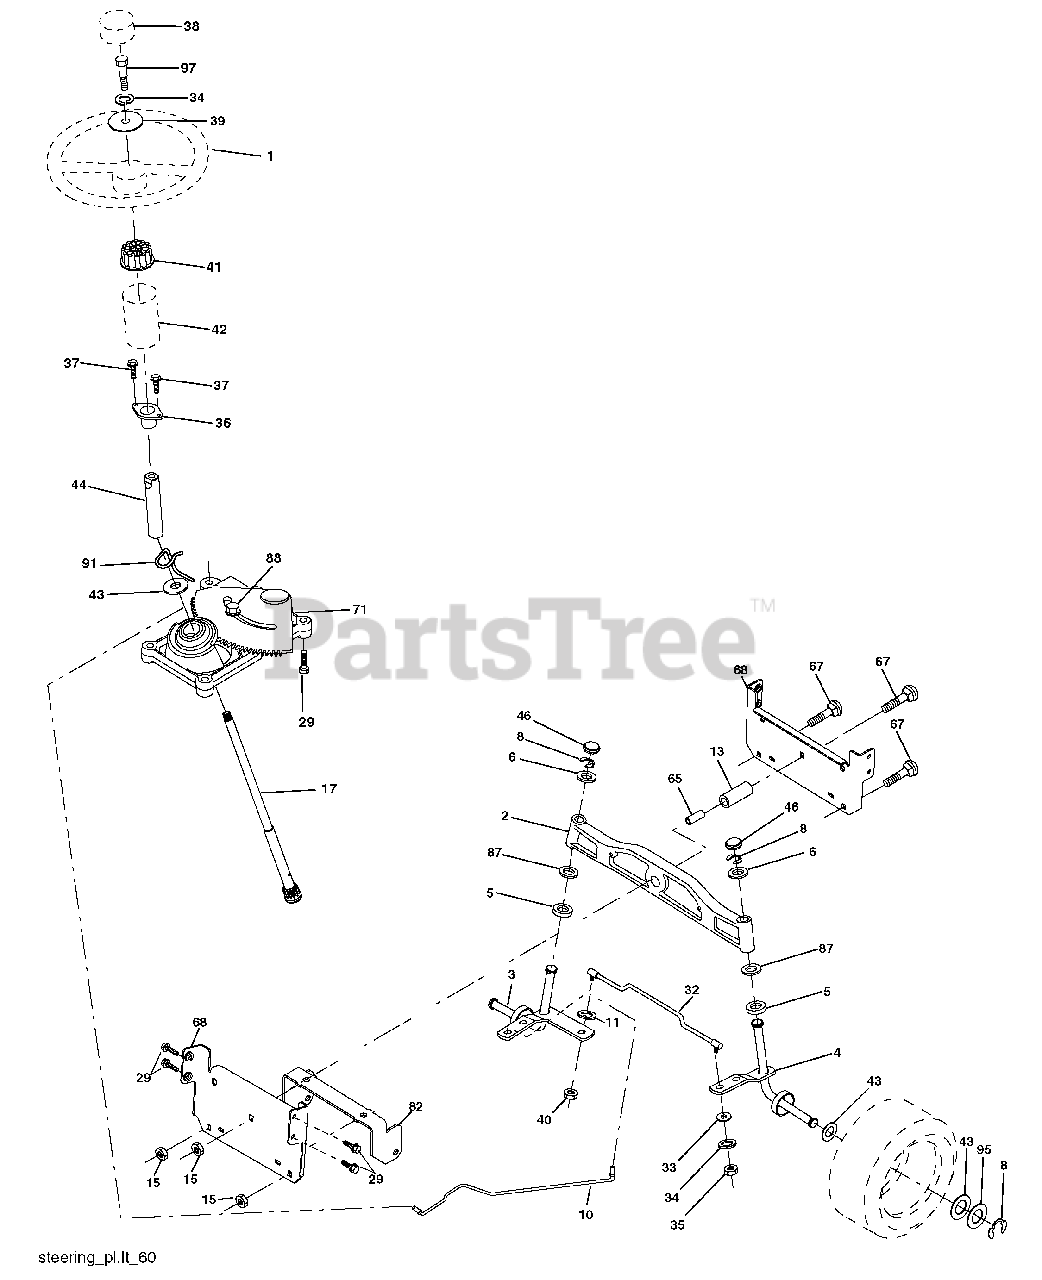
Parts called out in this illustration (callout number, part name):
1	Steering Wheel
2	Front Axle Assembly
3	Spindle Assembly, L.H.
4	Spindle Assembly, R.H.
5	Bearing, Race, Thrust, Hardened
6	Washer 25/32 x 1-5/8 x 16 Ga.
11	Washer, Lock
15	Nut Hex Flange Lock
17	Shaft Assembly, Steering
29	Screw 3/8-16 x 3/4
33	Washer 11/32 x 3/4 x 16 Ga.
34	Washer Lock Hvy Hlcl Spr 5/16
35	Crownlock Nut 5/16-24 unf
36	Bushing, Steering
37	Screw TT #I0-32 x 5 x 3/8 Flange
38	Cap Wheel Steering
39	Washer 11/32 ID x 2-3/8 OD 12 Ga.
40	Nut Crownlock 3/8-24
41	Adaptor, Steering Wheel
42	Boot, Steering Dash P/L Mtl
43	Washer 25/32 x 1-1/4 x 16 Ga.
44	Extension Steering
65	Spacer Axle
67	Bolt Rdhd Sq 3/8-16 x 2-1/4
71	Steering Asm.
82	Bracket Susp. Chassis Front
87	Washer Flat .781 x 1-1/2 x .14
88	Bolt Shoulder 7/16-20 unc
91	Clip Steering
95	Washer Hardened .739 x 1.637 x 060
97	Bolt 5/16-18 unc x 4" L Gr. 5
